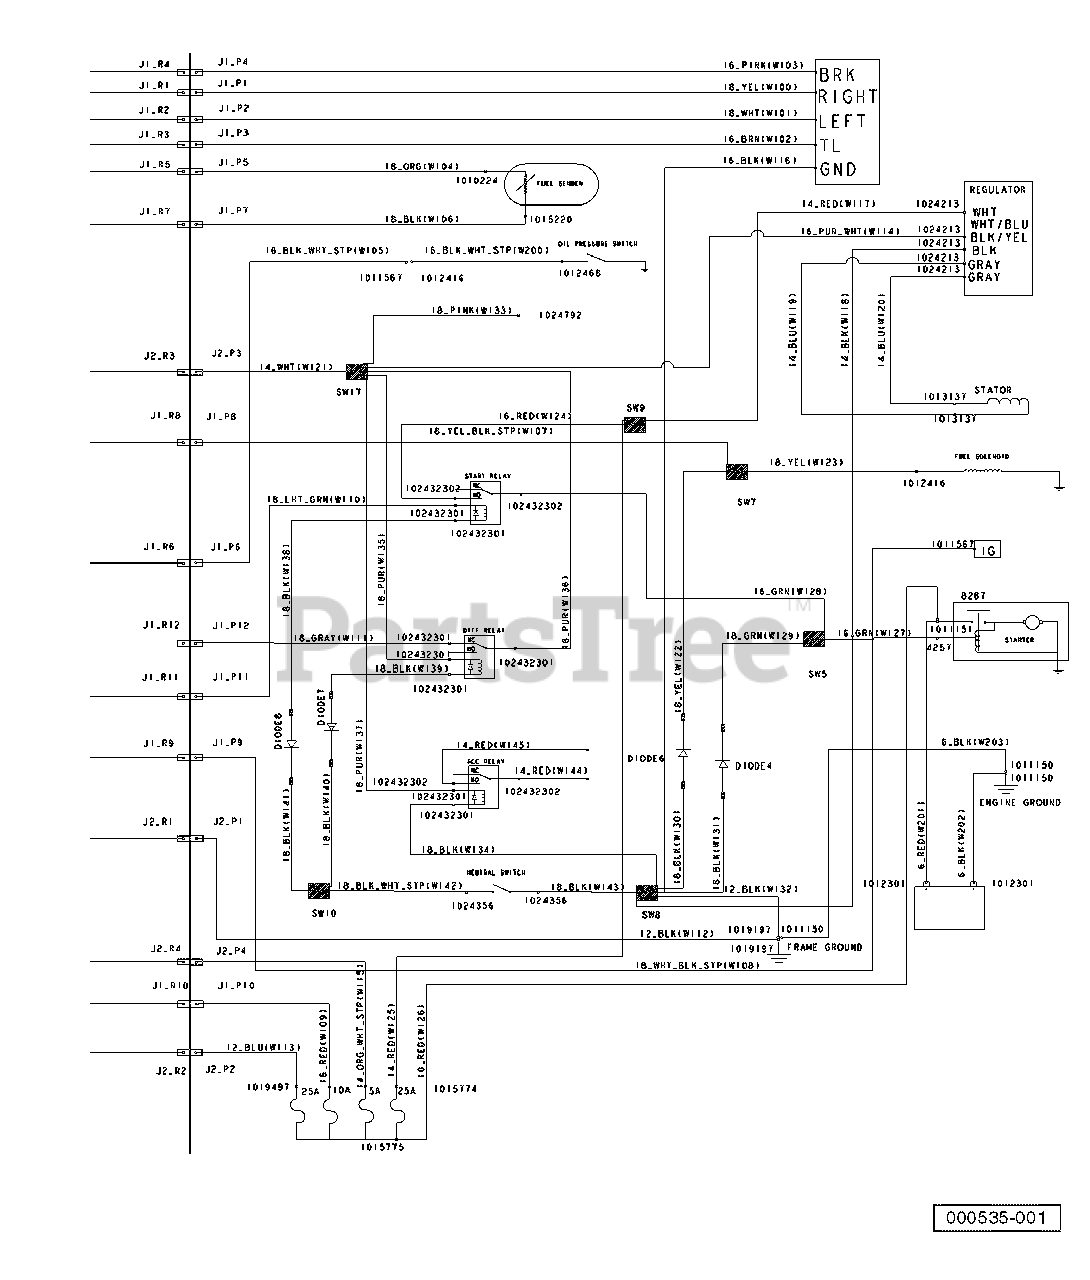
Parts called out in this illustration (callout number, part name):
1	Diode, General Purpose, 6.0a
2	Harness, Restyle Gas, Front
3	Harness, Restyle Gas, Rear
4	Asm, Switch, Limit
